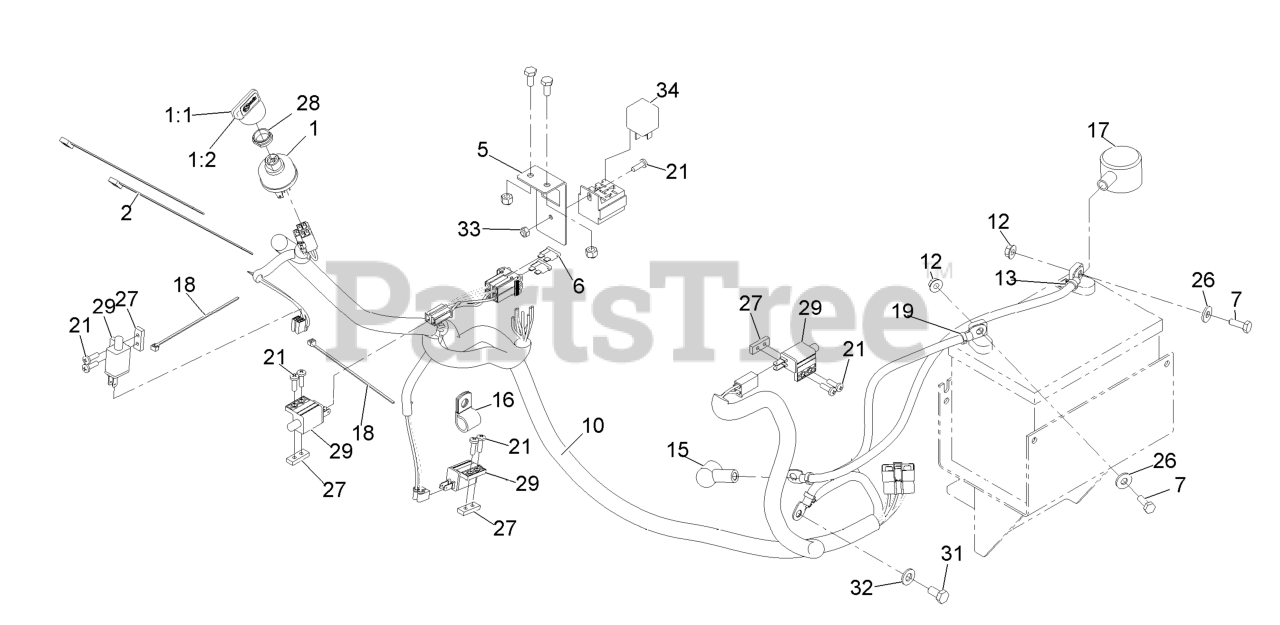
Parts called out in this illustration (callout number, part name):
1:1	KEYS-IGNITION (SPARE PAIR
1:2	KEY-IGNITION
2	TIE-PLASTIC
5	BRACKET-FUSE AND RELAY
6	FUSE-BLADE TYPE, 20 AMP
7	SCREW-HH
10	HARNESS-WIRE, TTS
13	ASM,POSITIVE BATTERY CABL
15	INSULATOR-SOLENOID
16	CLIP-LOOM
17	INSULATOR-BATTERY
18	TIE-CABLE
19	CABLE-BATTERY, NEGATIVE
21	SCREW-PPH
26	WASHER-FLAT
27	PLATE-TAPPED
28	NUT-SWITCH, IGNITION
29	SWITCH-OPEN, NORMALLY
31	SCREW-HH
32	WASHER-PLAIN
33	NUT-LOCK, NI
